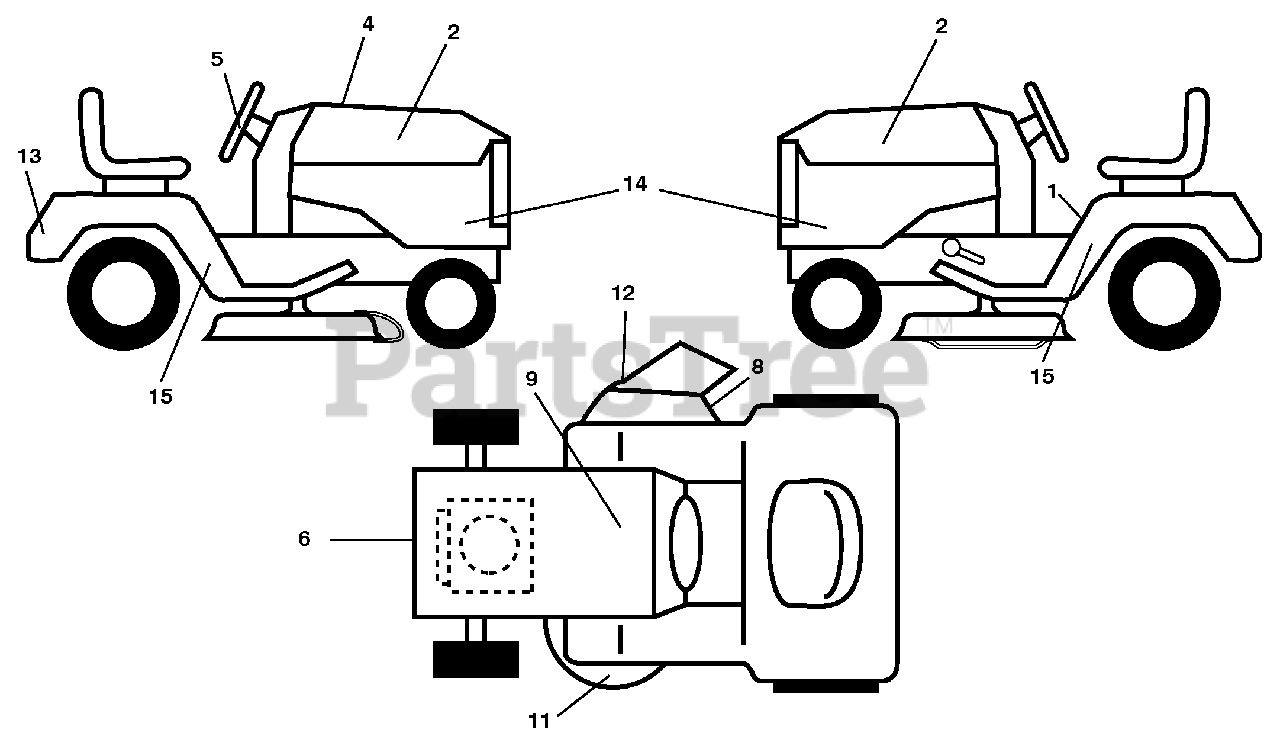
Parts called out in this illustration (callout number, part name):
1	Decal, Operator's
2	Decal, Hood RH/LH
4	Decal, Replacement
5	Decal, Strg Whl
6	Decal, Engine HP
8	Decal, Mower Sch.
9	Decal, Battery Dnge/Poi
11	Decal, Mower Caution
12	Decal, Mower Warning Keep Hand Away
13	Decal, Fender
14	Decal, Panel SD
15	Decal, Fender SD LH/RH
16	Decal, Fender SD RH
16	Decal, Bypass
16	Pad, Footrest, RH
16	Pad, Footrest, LH
